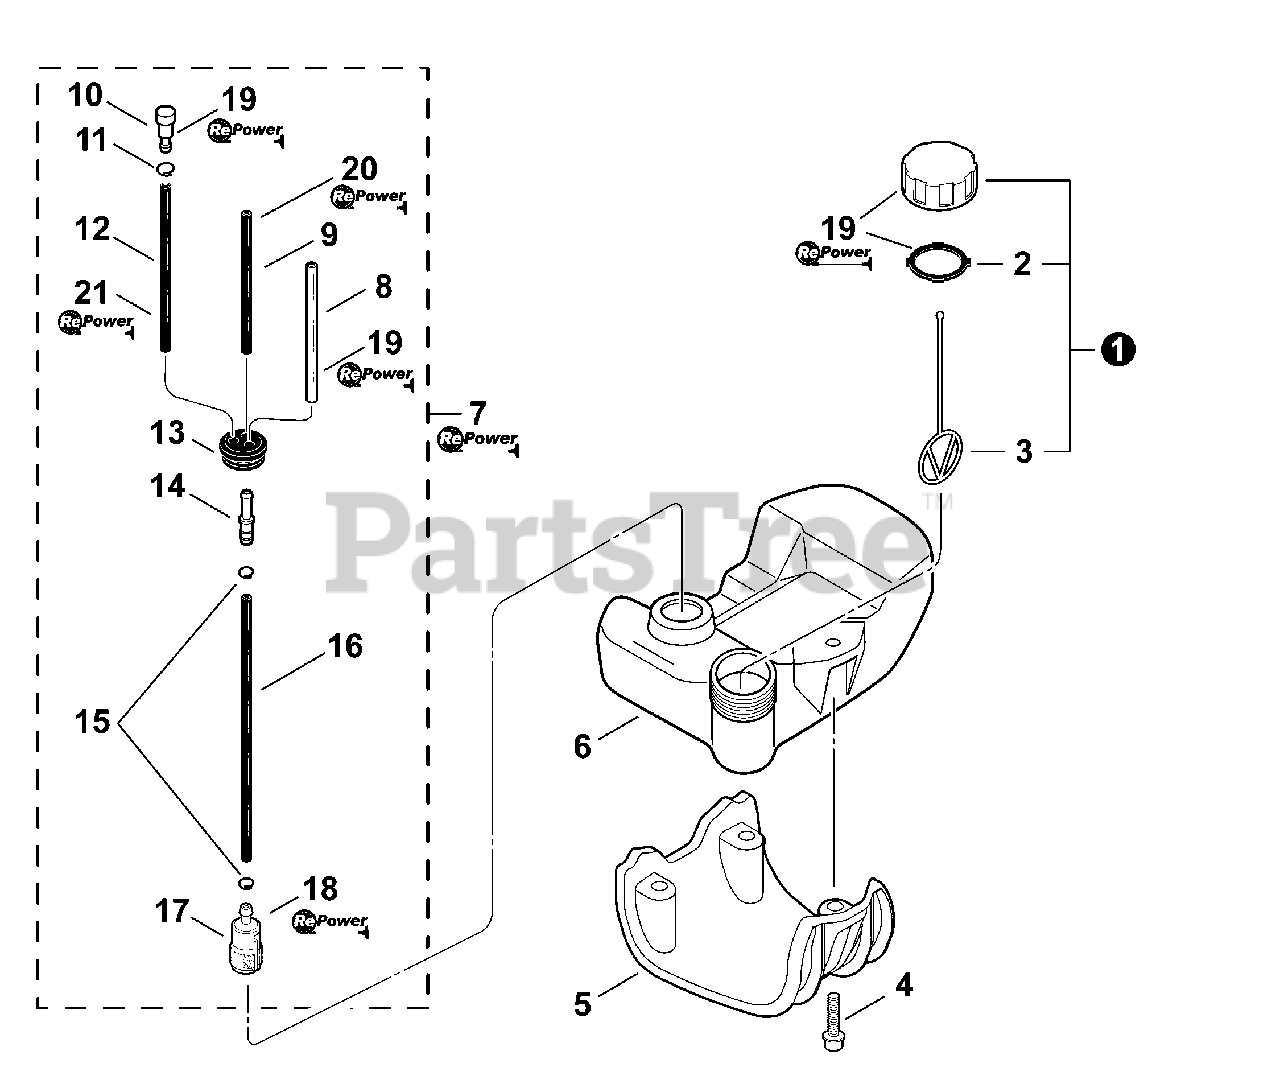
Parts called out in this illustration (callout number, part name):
1	CAP ASSY, FUEL
2	GASKET, FUEL CAP
3	CONNECTOR, CAP L= 100 MM
4	BOLT 5×20
5	GUARD, FUEL TANK
6	TANK, FUEL
7	FUEL SYSTEM KIT
8	PIPE, FUEL 3×6×80 CLEAR
9	PIPE, FUEL - 3×5×67 - BLACK
10	VENT ASSY
11	CLIP 6.5 MM
12	PIPE 3×6×115 BLACK
13	GROMMET, FUEL
14	CONNECTOR, PIPE Ø5ר3.5
15	CLIP Ø6
16	PIPE, FUEL - 3×5×125 - BLACK
17	FILTER, FUEL 125-528
18	TUNE-UP KIT - REPOWER
19	CAP/VENT KIT - REPOWER
20	BULK PIPE - 3×6 MM CLEAR (4 PIECES×2 M)
21	BULK PIPE - 3×5 MM BLACK (4 PIECES×2 M)
22	BULK PIPE - 3×6 MM BLACK (4 PIECES×2 M)
